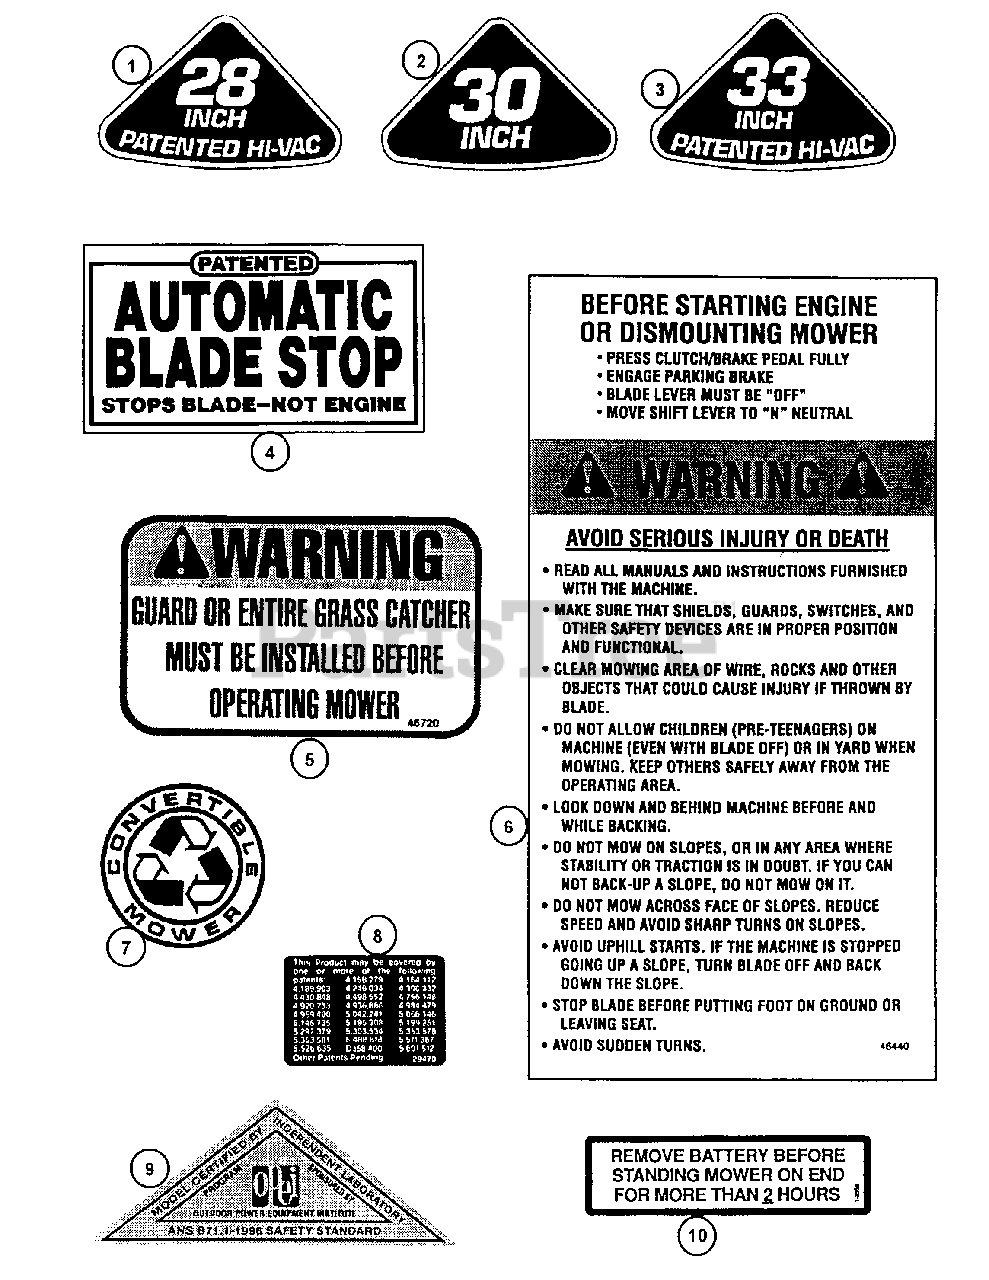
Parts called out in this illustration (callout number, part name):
1	DECAL, 28 Inch
2	DECAL, 30 Inch
3	DECAL, 33 Inch
4	DECAL, Auto Blade Stop
5	DECAL, Chute/Deflector Warning
6	DECAL, Safety Instructions
7	LOGO, Convertible Mower (Blue)
8	DECAL, Patent Numbers
9	DECAL, OPEI, Ride-On
10	DECAL, Battery
